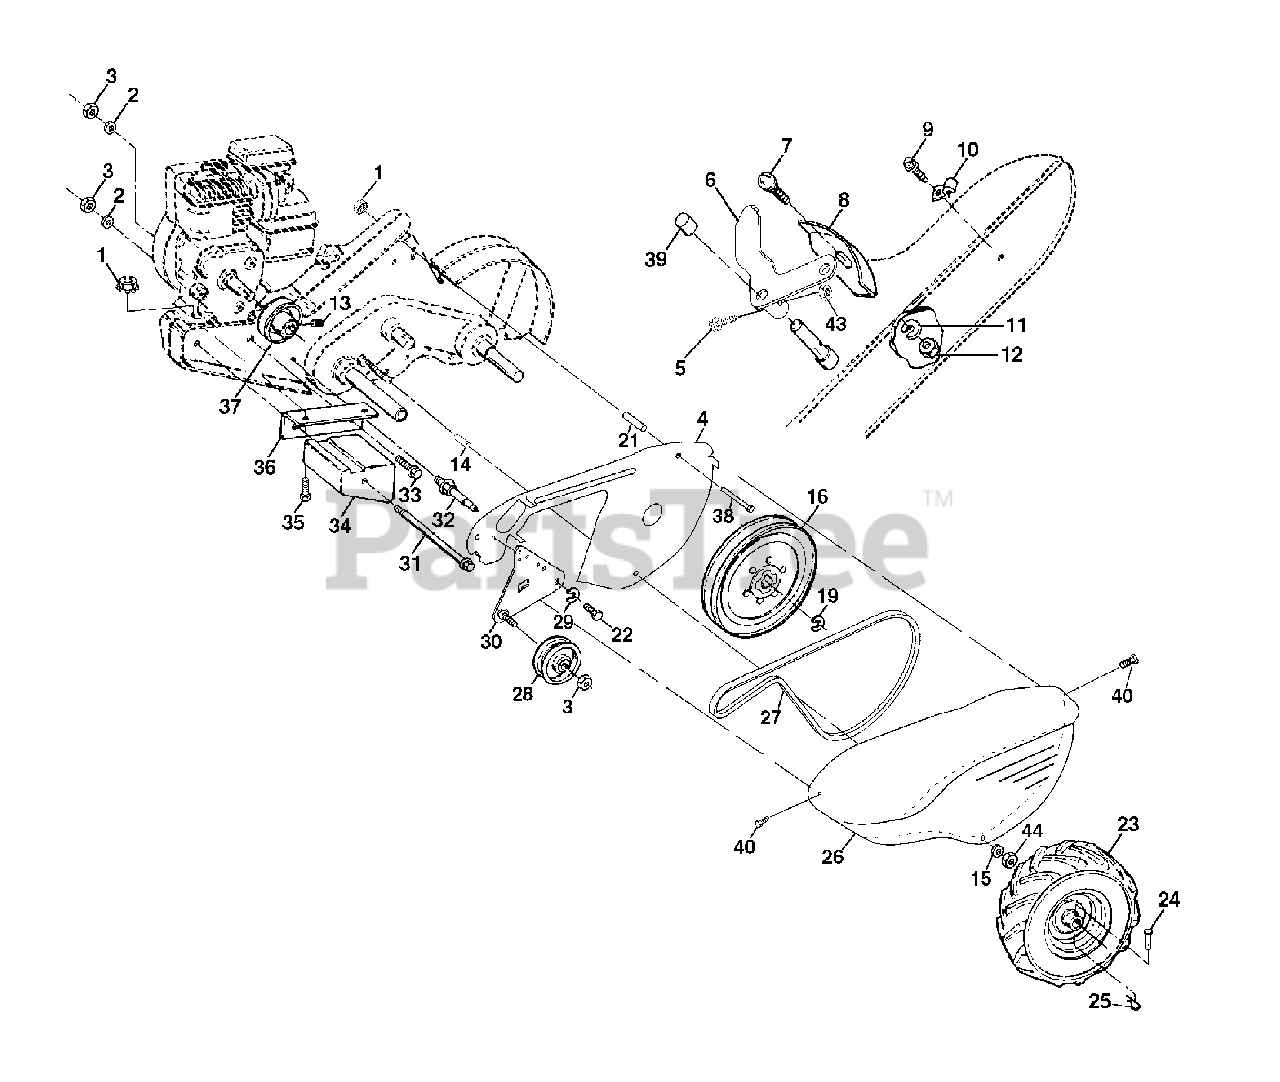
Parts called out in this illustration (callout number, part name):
1	Nut, Keps 5/16-18
2	Washer, Lock 3/8
3	Nut, Hex 3/8-16
4	Shield, Inner Belt Guard RT
5	Screw, Shift Lever
6	Lever, Shift
7	Bolt, Carriage 1/4-20 x 1/2 Gr. 5
8	Plate, Shift Indicator
9	Screw, Hex, Washer Head, Slotted #10-24 x 1/2
11	Washer, Lock 1/4
12	Nut, Hex 1/4-20
13	Screw, Set, Hex 5/16-18 x 3/8
14	Spacer, Split 0.327 x 0.42 x 2.09
15	Washer 11/32 x 11/16 x 16 Ga.
16	Sheave, Transmission
19	Retainer, Ring
21	Spacer, Split
22	Bolt, Fin Hex 5/16-24 UNF x 1/2
23	Rim
23	Tire Valve
24	Rivet, Drilled
25	Clip, Hairpin
26	Guard, Belt
27	Belt, V
28	Pulley, Idler
29	Ring, Klip
30	Bracket, Idler
31	Bolt, Hex 5/16-16 x 12
32	Shaft, Idler Arm
33	Bolt, Hex 3/8-16 x 1
34	Counterweight, L.H.
35	Bolt, Hex 5/16-18 x 2
36	Bracket, Reinforcement, L.H.
37	Sheave, Engine
38	Bolt, Fin Hex 5/16-18 UNC x 2-3/4
39	Cap, Plunger Blk
40	Screw Hex Wsh Slt #10-24 x 1/2
43	Nut, Lock #10-24
44	Nut Lock Hex w/Ins 5/16-18 Unc PL
